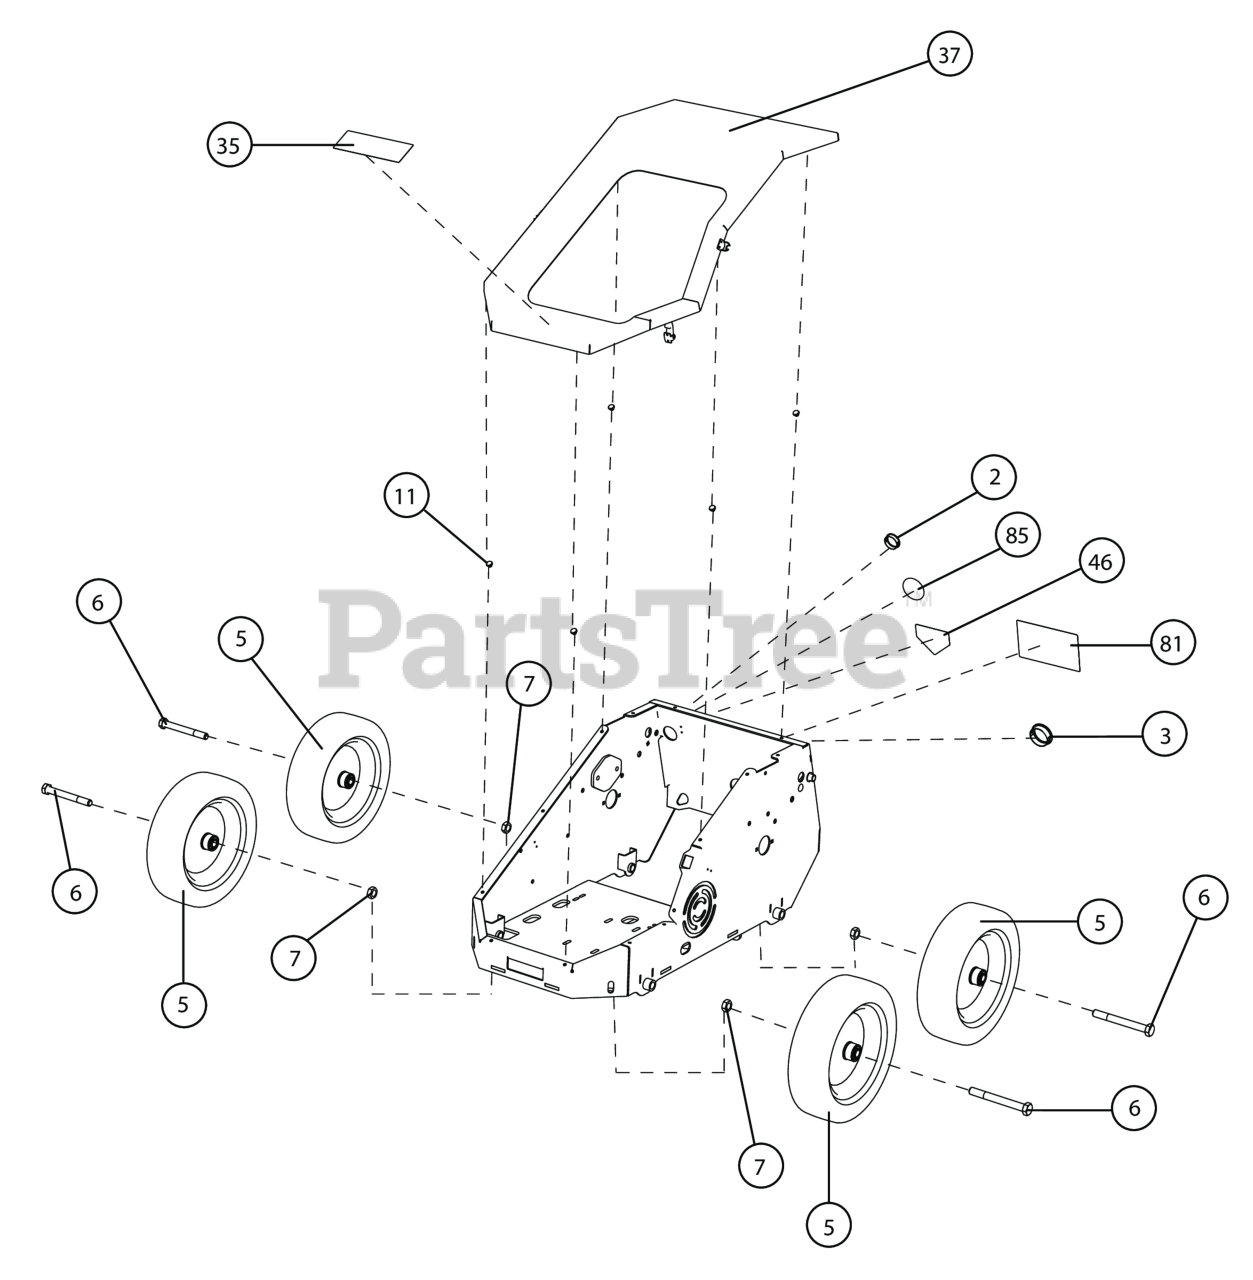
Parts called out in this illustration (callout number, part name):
2	BUSHING, SNAP 1.31" ID
3	BUSHING, SNAP 1.81" ID
5	SEE: 382606
6	SCR-CAP, HEX .625"-11 X 5.500" G5 ZP
7	NUT JAM, 5/8-11 ZP
11	RUBBER BUMPER PUSH IN
35	LABEL BADGING PLUGR PL415
37	COVER WA PL18 BOELS SERVICE
46	LABEL WARNING OPEI
81	LABEL AERATING INST PL
85	LABEL ROUND CORE T2V 2.5"
